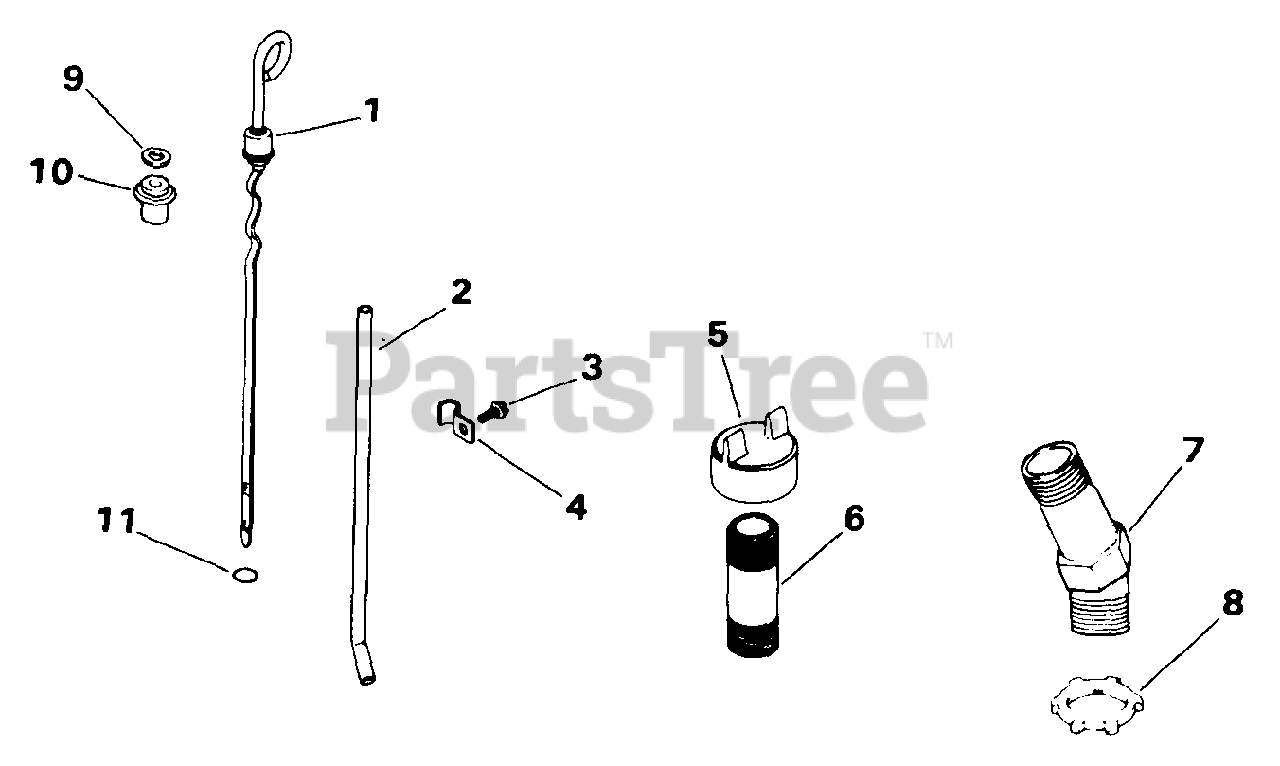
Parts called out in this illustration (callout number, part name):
1	DIPSTICK - DISCONTINUED
3	SCREW, WSH HD TAP #10-32X7/16" USE 25 086 101-S
5	CAP - (#DSC)
